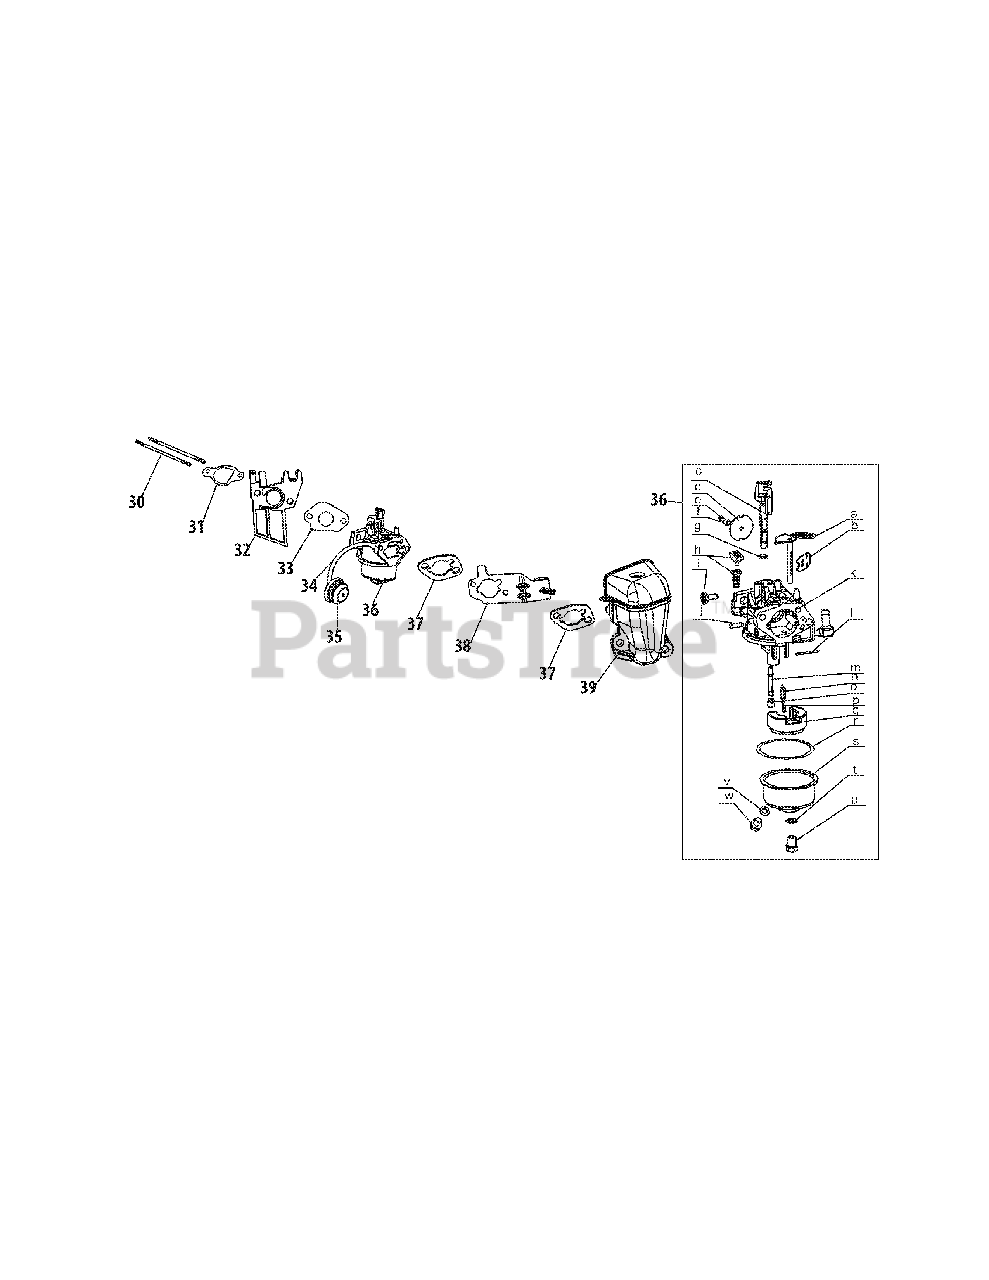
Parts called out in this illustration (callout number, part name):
30	Stud M6×92
31	Gasket, Carburetor Insulator
32	Insulator, Carburetor
33	Gasket, Carburetor
34	Fuel Hose 3.2×6.5×150
36	Carburetor
37	Gasket, Air Filter
38	Choke Controller Assembly
39	Heater Box
